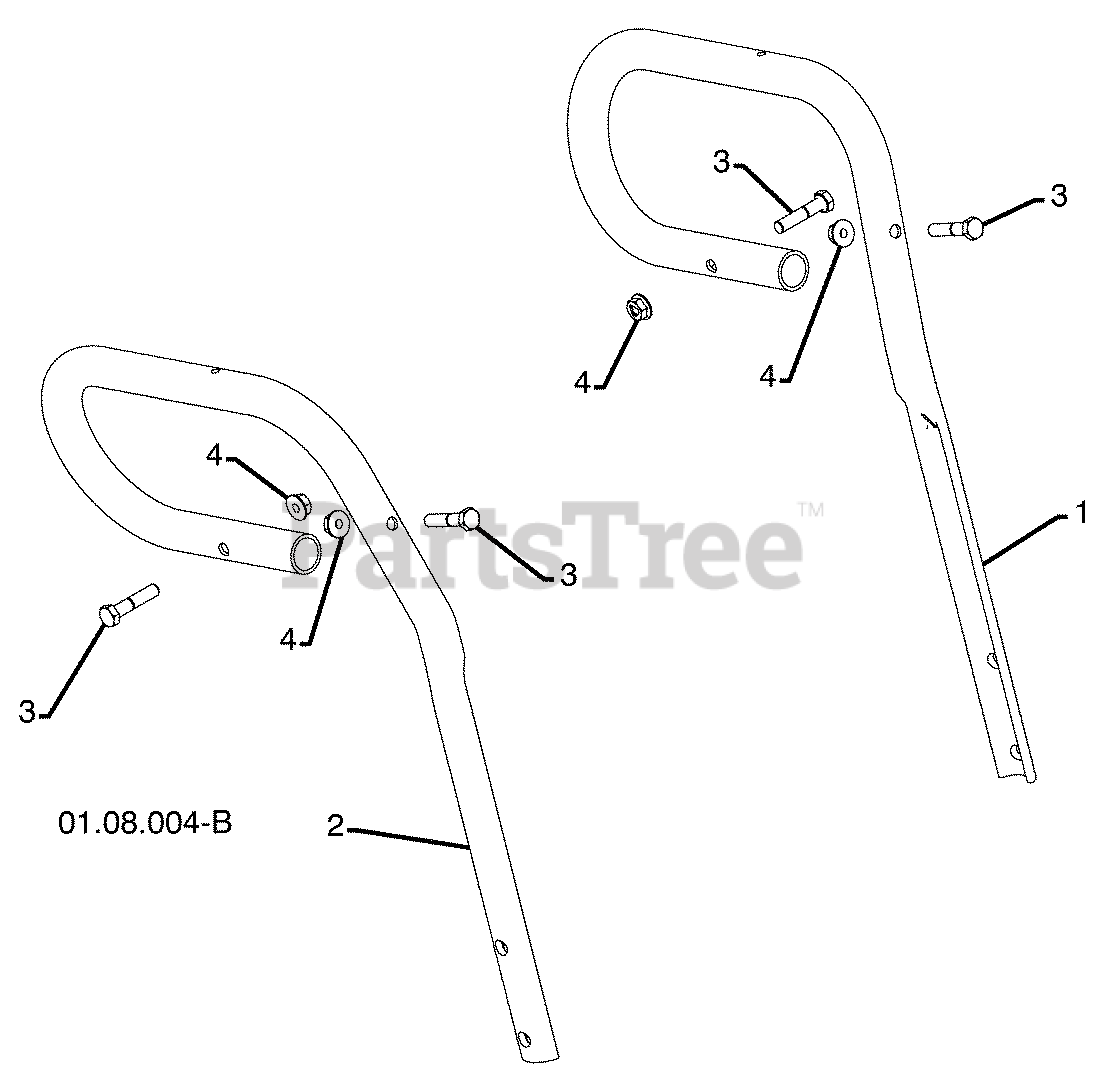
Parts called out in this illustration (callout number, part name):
1	LOOP HANDLE LH
2	LOOP HANDLE RH
3	SCREW 5/16-18 X 1.50
4	NUT 5/16-18
